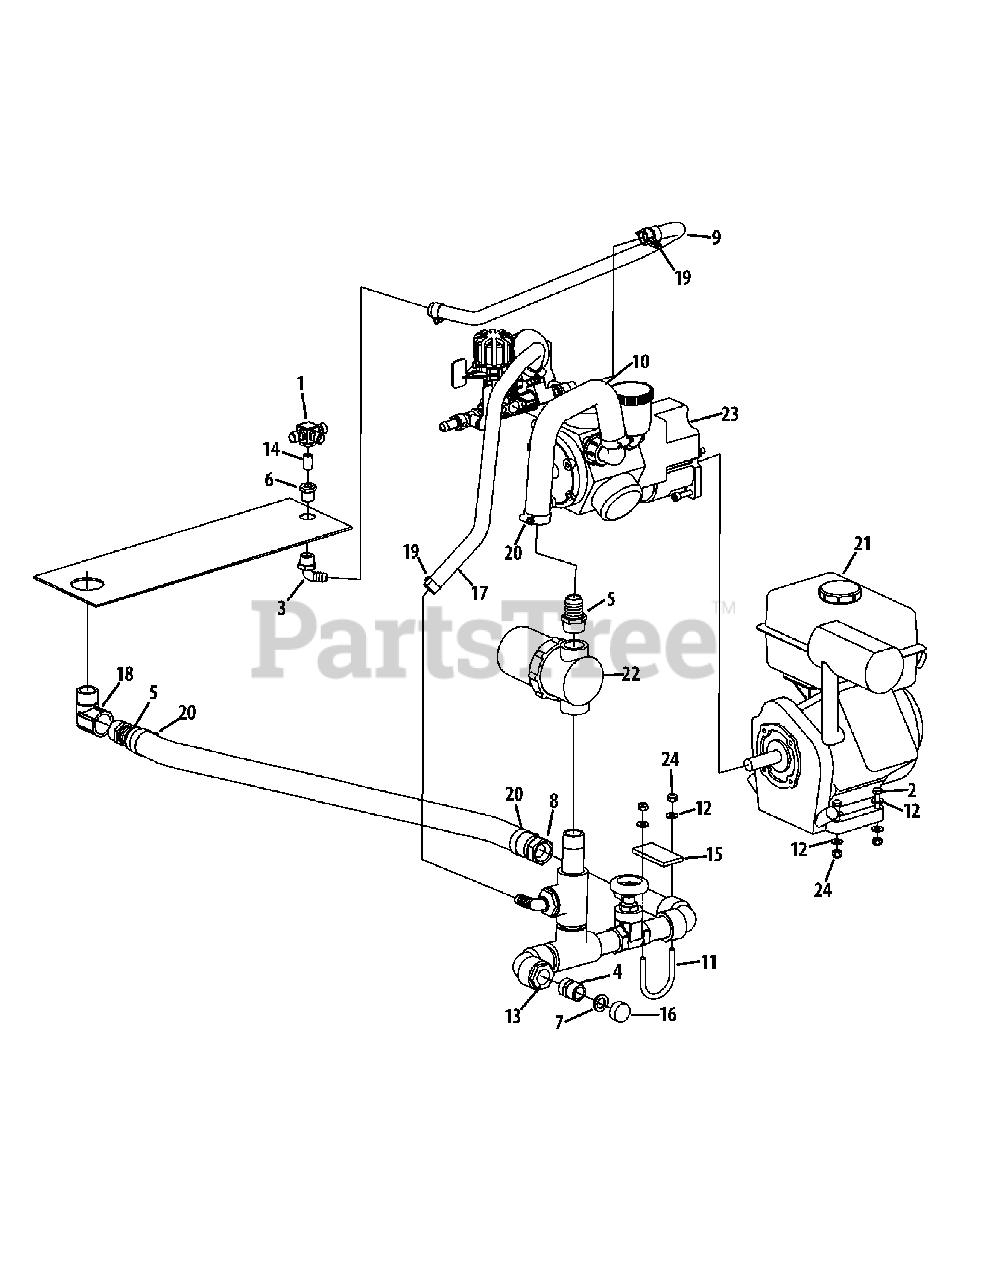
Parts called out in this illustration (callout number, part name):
1	Jet Agitator
2	Hex Screw, 5/16-18 x 1.75
3	90° Elbow, 1/2 x 1/2
4	Threaded Pipe Hose, 3/4 x 3/4
5	Insulated Male Hose, 1 x 1
6	Reducer Bushing, 1/2 x 1/4
7	Hose Washer, 3/4
8	Female Hose Repair End, 1
9	Hose, 1/2
10	Spirafl ex Hose, 1
11	Carriage Bolt, 5/16-18 x 2.62 x 2.30
12	Washer, .344 x .688 x .063
13	Manifold Assembly, 100/200/300
14	Brass Nipple, 1/4
15	Rubber Pad, 1/4 x 1-1/2 x 3
16	Brass Hose Cap, 3/4
17	Reinforced Hose, 5/8
18	Elbow, 1 x 90
19	Hose Clamp
20	Hose Clamp
21	Kawasaki Engine
22	Mesh Bowl Strainer
23	Hypro Pump
24	Hex Lock Nut, 5/16-18
